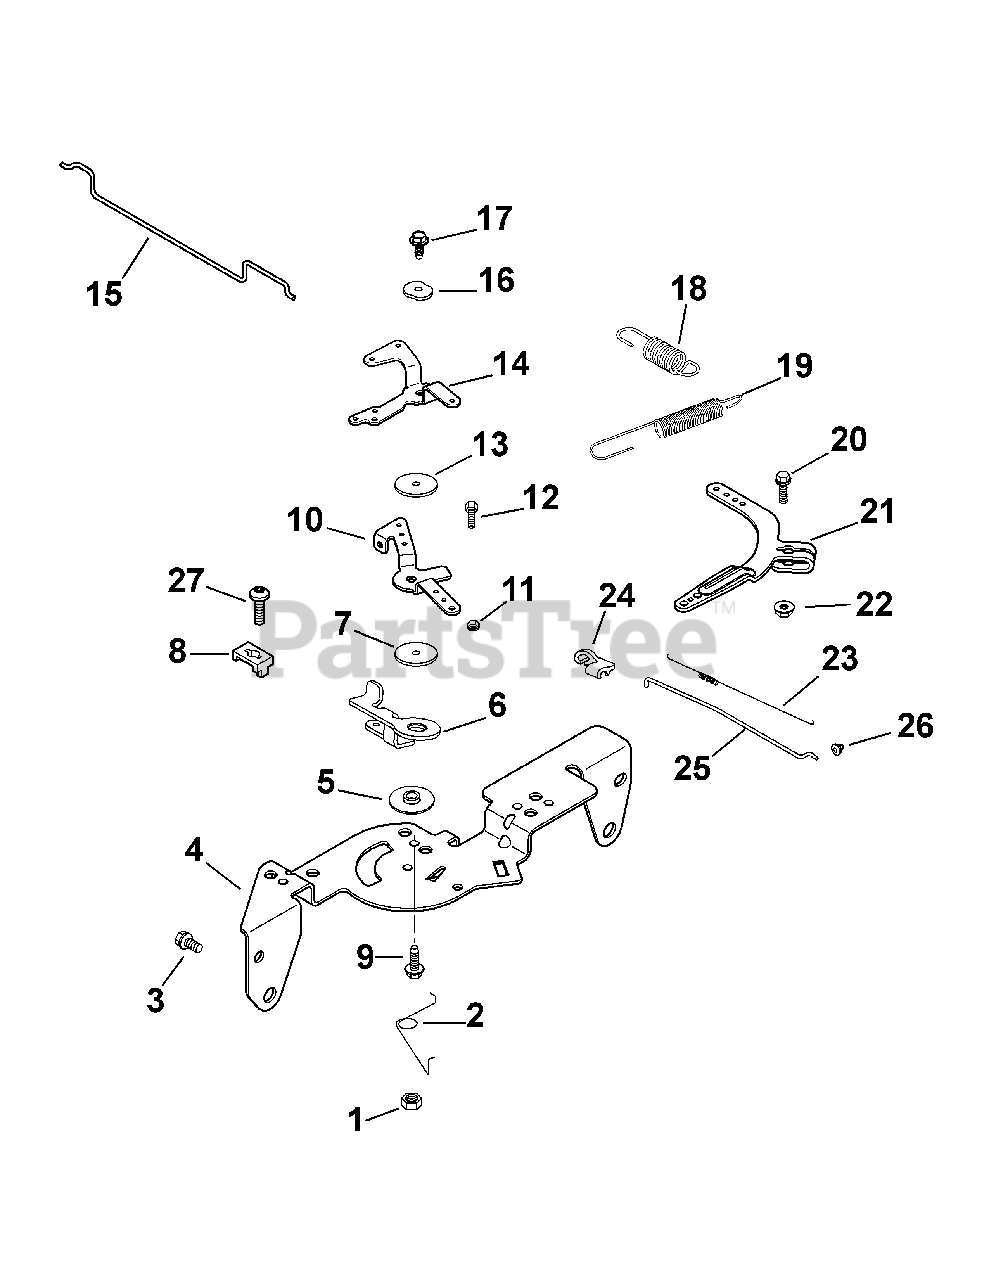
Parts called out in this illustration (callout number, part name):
1	Nut, hex. lock M5x0.8
2	Spring, choke return
3	Screw, hex flange M6x1.0x16
4	Bracket, control
5	Spacer, control assembly
6	Lever, throttle actuator
7	Washer, flat, 5mm
8	Clamp, cable
9	Screw, hex. flange M5x0.8x16
10	Lever, throttle control
12	Screw, cap M4x0.7x30
13	Washer, flat, 5.5 mm
14	Lever, choke
15	Linkage, choke
16	Washer, spring 1/4"
17	Screw, hex. flange M5x0.8x20
18	Spring, governor
19	Spring, governor
20	Bolt, rd hd sq neck, M6x1.0x25
21	Lever, governor
22	Nut, flange M6x1.0
23	Spring, linkage
24	Bushing, linkage retaining
25	Linkage, throttle
26	Bushing, throttle linkage
27	Scr, lbd thd frm, M5 x 0.8 x 16
